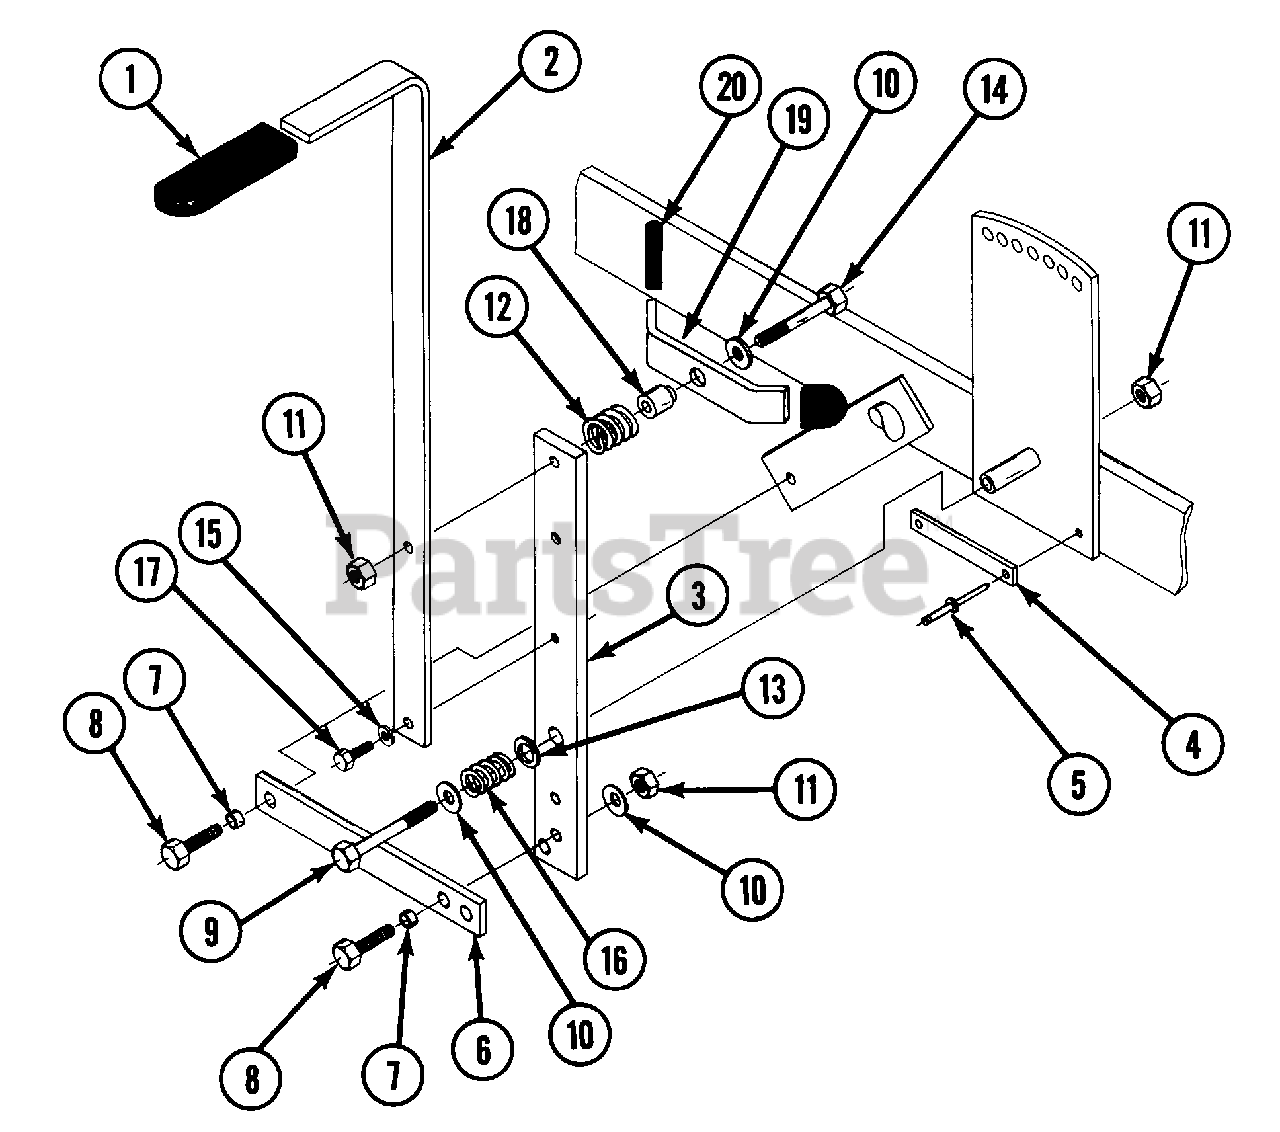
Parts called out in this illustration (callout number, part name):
1	GRIP, VINYL, 1/4 X 1
2	HANDLE, DECK LIFT, TOP
3	DECK HANDLE WELDMENT
4	SLIDE, DECK HANDLE
5	BLIND (POP) RIVET
6	DECK LIFT CONNECTOR
7	BUSHING CONNECTOR
8	CAPSCREW, HEX, 3/8-16 X 1-1/4, GRADE 5
9	CAPSCREW, HEX, 3/8-16 X 2-3/4, GRADE 5
10	WASHER, 3/8 STD FLAT, W SERIES
11	LOCKNUT, HEX, 3/8-16 W/NYLOC
12	SPRING, COMPRESSION
13	WASHER, .656 ID X 1 OD X 8 GA 2-3/8
14	CAPSCREW, HEX, 3/8-16 X 2-3/8, GRADE 5
15	LOCKWASHER, 5/16 HEAVY, SPLIT SPRING
16	SPRINGER COMPRESSION
17	CAPSCREW, HEX, 5/16-18 X 3/4, GRADE 5
18	LOCK STAND
19	LOCK ARM
20	GRIP, LOCK
